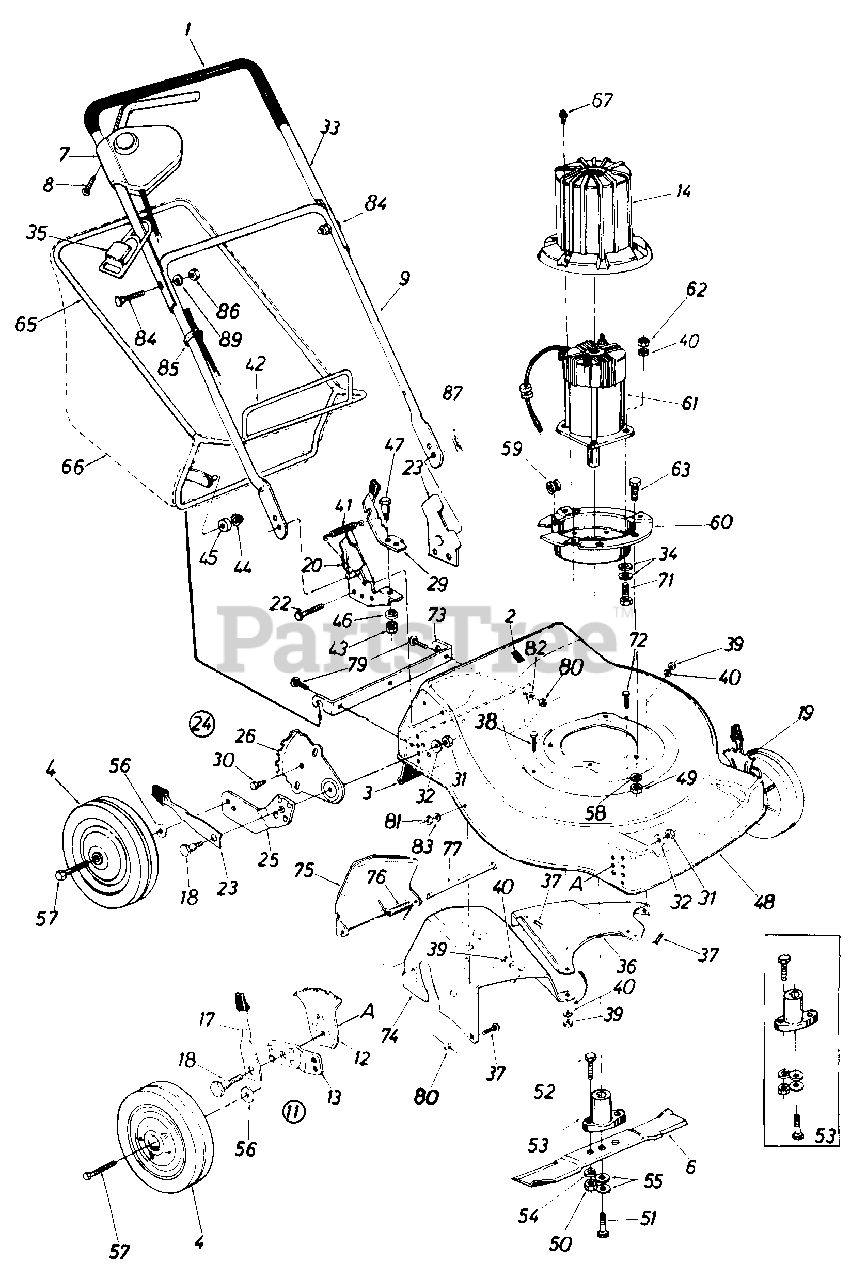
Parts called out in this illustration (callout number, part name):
1	Grip-22"
3	Rear Flap Ass'y.
4	Wheel Ass'y. Comp. 8 x 1.75
6	20" Blade
7	Control w/Cord
8	Truss Mach. AB-Tap. Scr.
9	Lower Handle
11	Front Height Adj. Ass'y. R.H.
12	Front Index Plate
13	Front Pivot Bar
14	Shroud
17	Spring Lever w/Knob
18	Shoulder Bolt .50" Dia. x .375
19	Front Height Adj. Ass'y. L.H.
20	Handle Brkt. Ass'y.R.H.
22	Hex Wash. Hd. AB-Tap Scr. 1/4" x.62" Lg.
23	Spring Lever w/Knob
24	Rear Height Adj. Ass'y. R.H.
25	Rear Pivot Bar-R.H.
26	Rear Index Plate
29	Lock Lever
30	Hex Wash. Tap Scr. 1/4 x .62" Lg.
31	Hex Nut 3/8-16 Thd.
32	L-Wash. 3/8" I.D.*
33	Upper Handle
34	Fl-Wash. 3/8" I.D. x 1.0" O.D.
35	Restraint
36	Rear Chute Baffle-L.H.
37	Carr. Bolt 1/4-20 x .50" Lg.
38	Hex Bolt 1/4-20 x .88" Lg.
39	Hex Nut 1/4-20 Thd.
40	L-Wash. 1/4" I.D.
41	Extension Spring
44	Push Cap 3/8" Rod
45	Plastic Roller
46	L-Wash. 5/16" I.D.
47	Shoulder Bolt
50	Hex Nut 5/16-24 Thd.
51	Hex Bolt 5/16-24 x .75" Lg.
52	Hex Bolt 5/16-24 x 1.00" Lg.
53	Blade Adapter Kit
54	L-Wash. 5/16" I.D.
55	Bell-Wash. .345" I.D. x .88" O.D.
56	Bell-Wash. .400" I.D. x .88" O.D.
57	Shld. Scr. .498" Dia. x 1.45"
58	L-Wash. 3/8" I.D.
59	Cord Restraint
60	Adapter Plate
62	Hex Jam Nut 1/4-20 Thd.
63	Hex Bolt 3/8-16 x 1.00" Lg.
65	Grass Catcher Upper Frame
66	Grass Bag (Without Flip Top)
67	Hex Wash. Hd. F-Tap Scr. #10-32 x 5/16" Lg.
71	Hex Bolt 1/4-20 x 1.00" Lg
72	Hex Wash. Hd. Self-Tap Scr. 1/4-20 x . 75" Lg.
73	Grass Catcher Hitch Brkt.
74	Rear Chute Baffle-R.H.
75	Chute Door
76	Torsion Spring
77	Hinge Pin .25" Dia. x 7.25" Lg.
79	Carr Bolt 1/4-20 x .75" Lg.
80	Hex Sems Nut 1/4-20 Thd.
81	Hex Nut 1/4-20 Thd.*
82	Fl-Wash. .281" I.D. x 1.25 O.D.
83	L-Wash. 1/4" I.D.
84	Curved Carr. Bolt 5/16-18 x 1.38" Lg.
85	Cable Tie
86	Hex Nut 5/16-18 Thd.
87	Hairpin Coter
89	L-Wash. 5/16" I.D.
